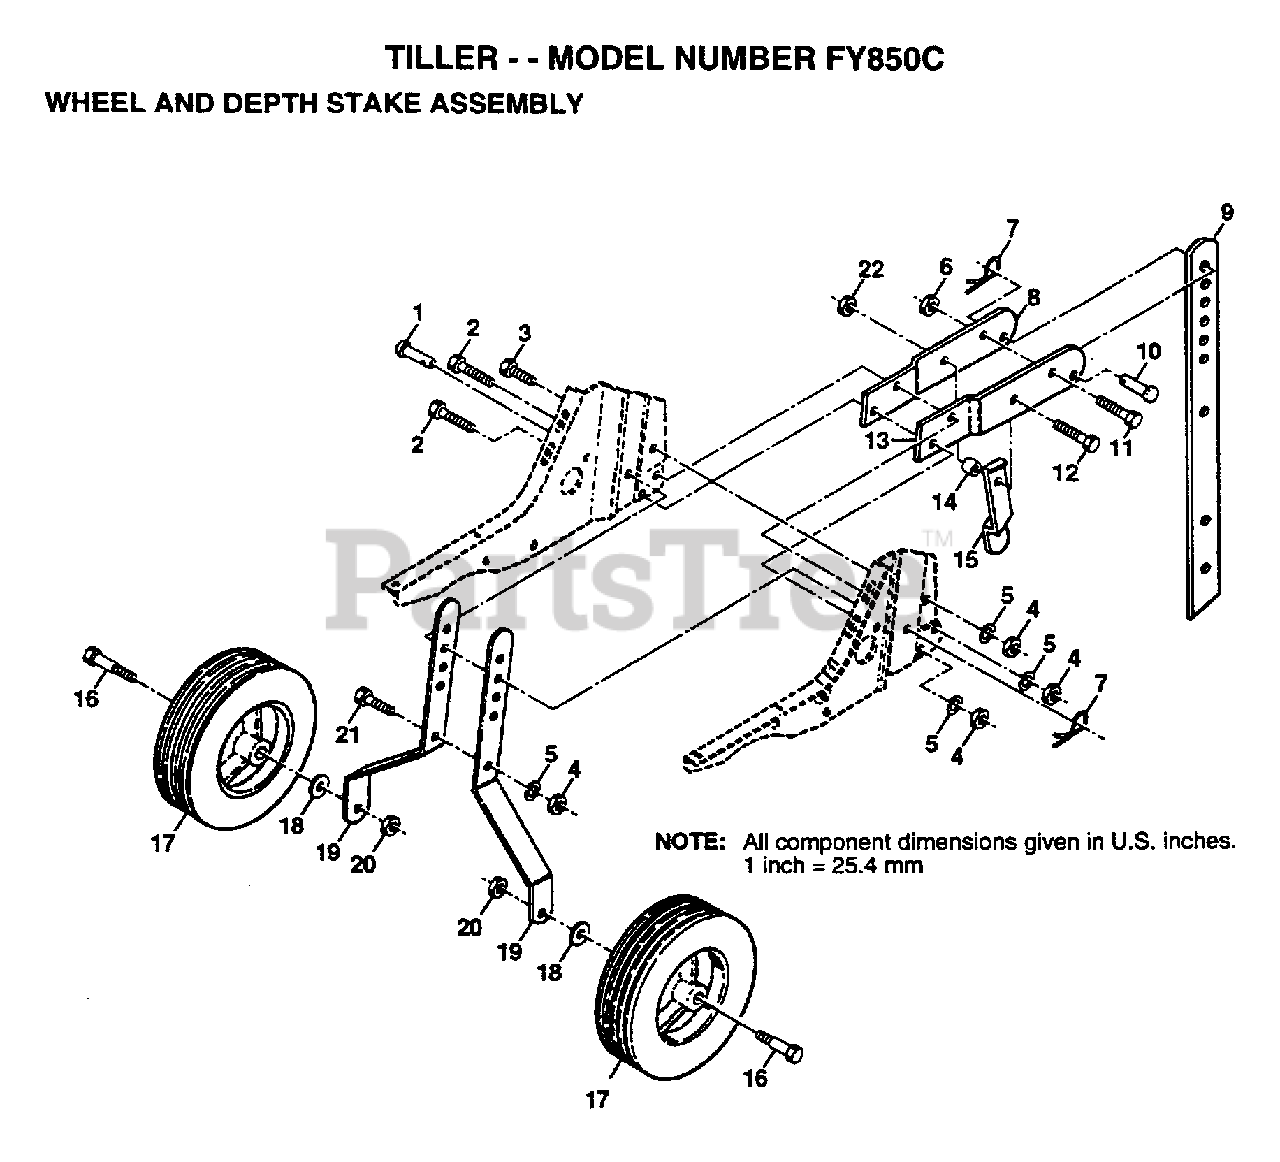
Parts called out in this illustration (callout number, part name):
1	DRILLED RIVET RT
3	BOLT
4	NUT.HEX.5/16-18
5	LOCKWASHER
6	NUT
7	SPRING.RETAINER
8	SUPPORT STAKE RH
11	BOLT
12	BOLT.HEX.5/16-1.5
13	SUPPORT STAKE LH
14	WASHER
15	STAKE SPRING TI
16	BOLT SHOULDER
18	WASHER
19	BRACKET.WHL.PNT.
22	NUT
